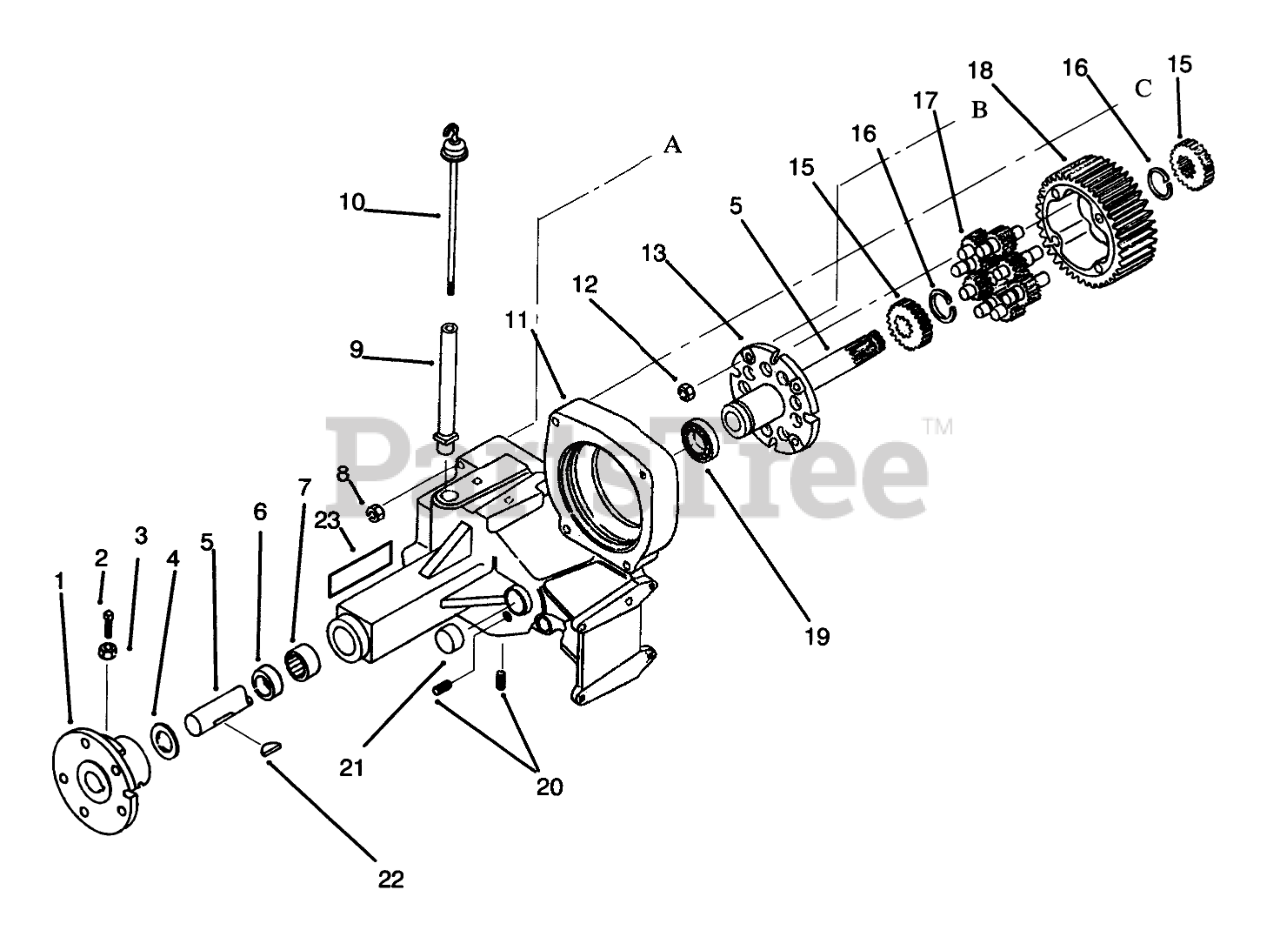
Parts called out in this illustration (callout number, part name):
1	Hub Rear
2	SCREW-SET, SQH
3	NUT-JAM
4	WASHER-THRUST
5	AXLE-REAR RH
6	SEAL-OIL
7	BEARING
8	NUT-LOCK, NI
9	NIPPLE-TRANS FILL
10	Dipstick
11	Case-Transaxle, RH (Incl. Ref.#23)
12	NUT
13	END CAP-DIFFERENTIAL
15	GEAR-AXLE DIFFERENTIAL
16	RING-SNAP
17	GEAR-PINION, 11T
18	GEAR-DIFFERENTIAL RING, 43T
19	BEARING-BALL
20	PLUG
21	BEARING-NEEDLE
22	KEY-WOODRUFF
23	DECAL - DANGER
